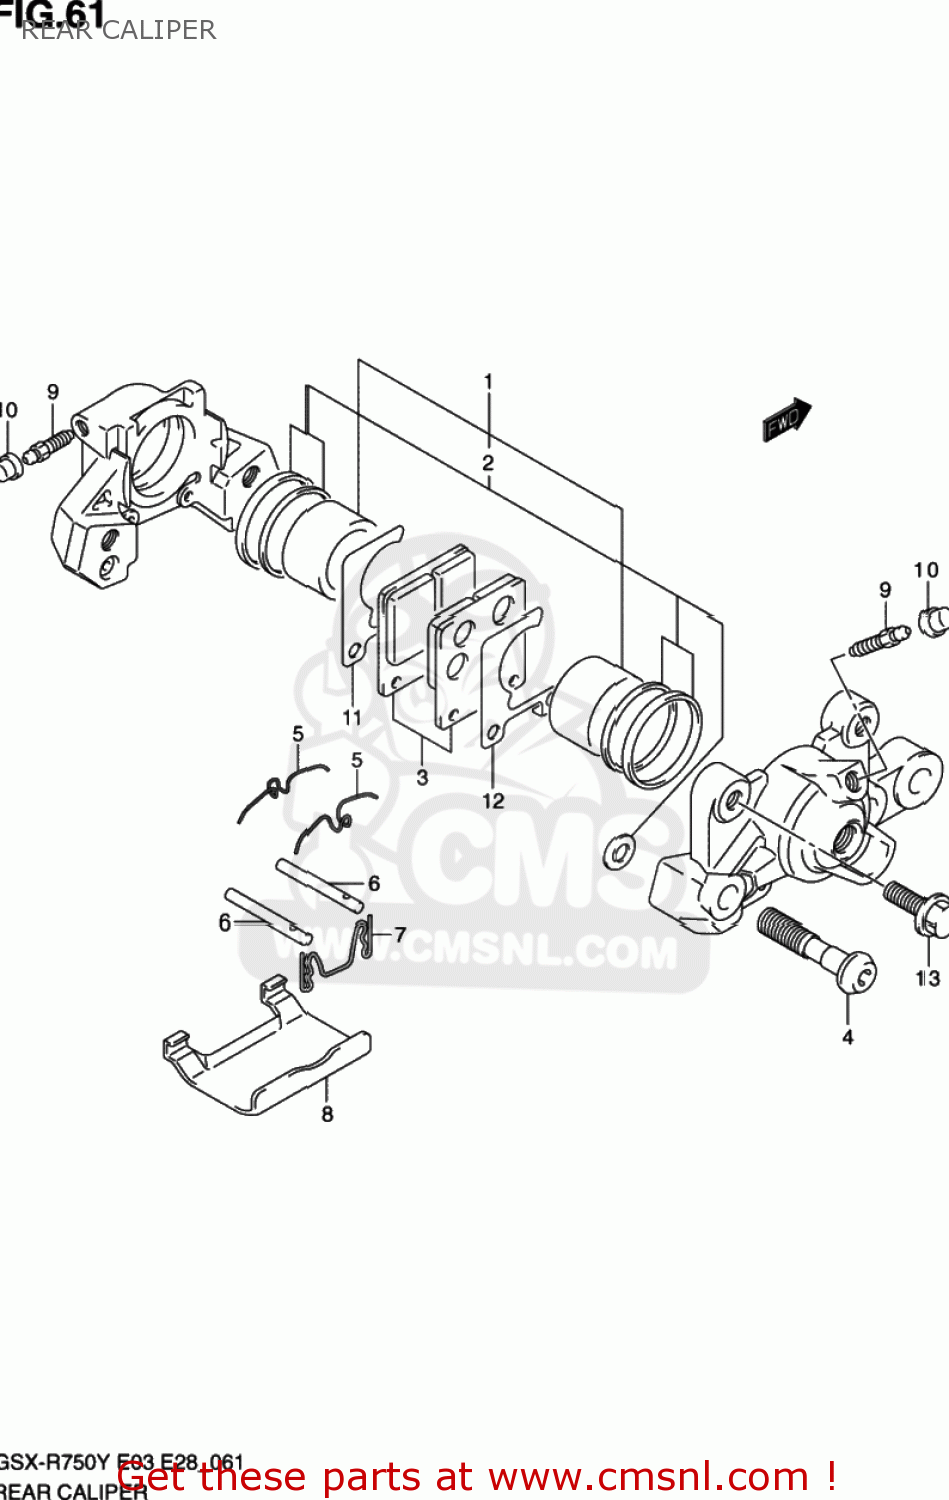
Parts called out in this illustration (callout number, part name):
1	PISTON SET
2	SEAL SET,PISTON
3	PAD SET (NAS)
4	BOLT,HOUSING
5	SPRING
6	PIN,PAD
7	CLIP,PAD PIN
8	COVER
9	BLEEDER
10	CAP,BLEEDER PLUG
11	SHIM,INNER
12	SHIM,OUTER
13	BOLT(8X28)
